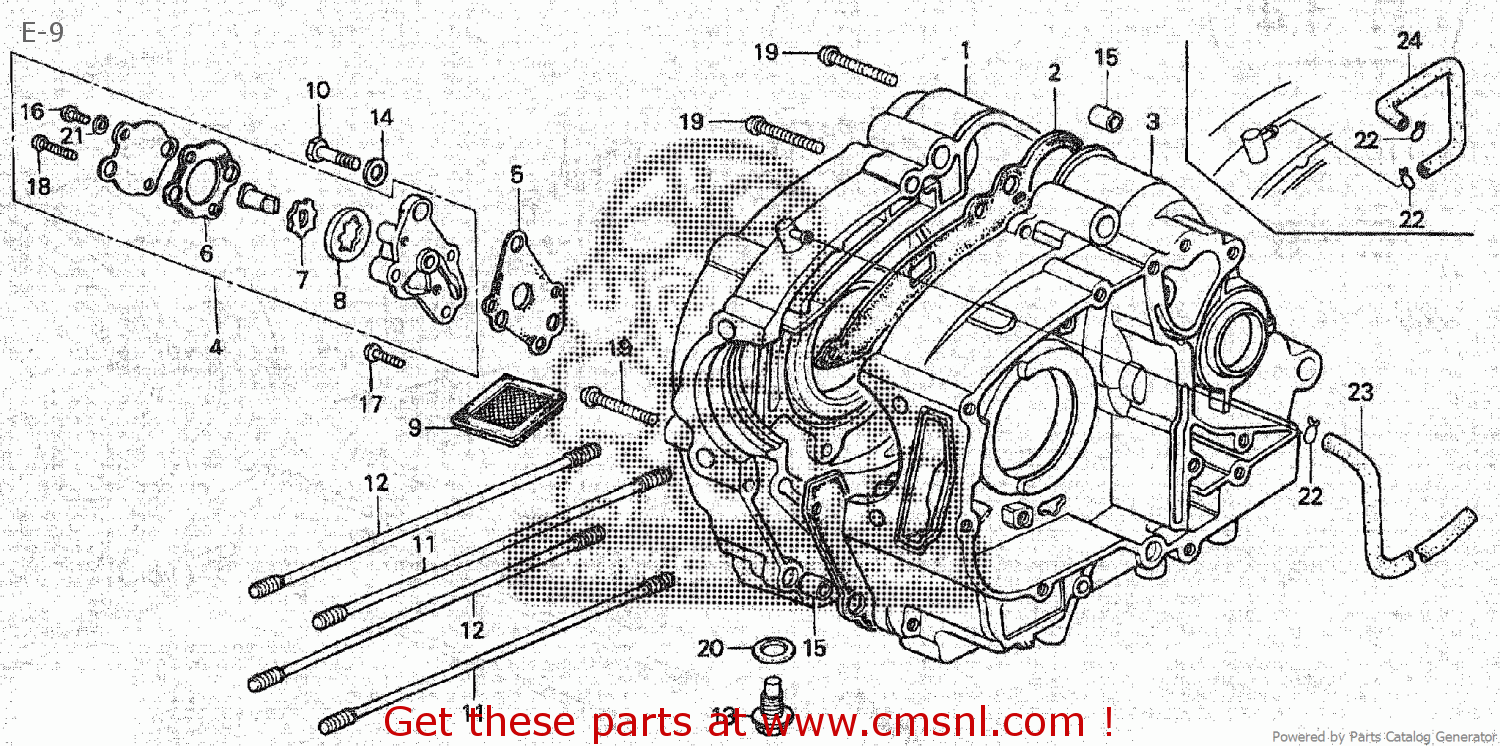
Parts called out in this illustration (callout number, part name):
1	CRANKCASE COMP,R.
2	GASKET,CRANK CASE (MCA)
3	CRANK CASE,L
4	PUMP ASSY.,OIL
5	GASKET,OIL PUMP (MCA)
6	GASKET PUMP COVER (NAS)
7	ROTER,OIL PUMP
8	ROTER,OIL PUMP
9	SCREEN, FILTER
10	BOLT, OIL JOINT
11	STUD A, CYLINDER
12	STUD B, CYLINDER
13	BOLT,DRAIN PLUG (JDM)
14	PACKING,OIL TOINT
15	PIN,DOWEL,10X14
16	SCREW,CROSS,5X12
17	SCREW,CROSS 6X16
18	BOLT,HEX 6X25
19	SCREW 6X40
21	WASHER,SPG.,5MM
23	TUBE,5X430
